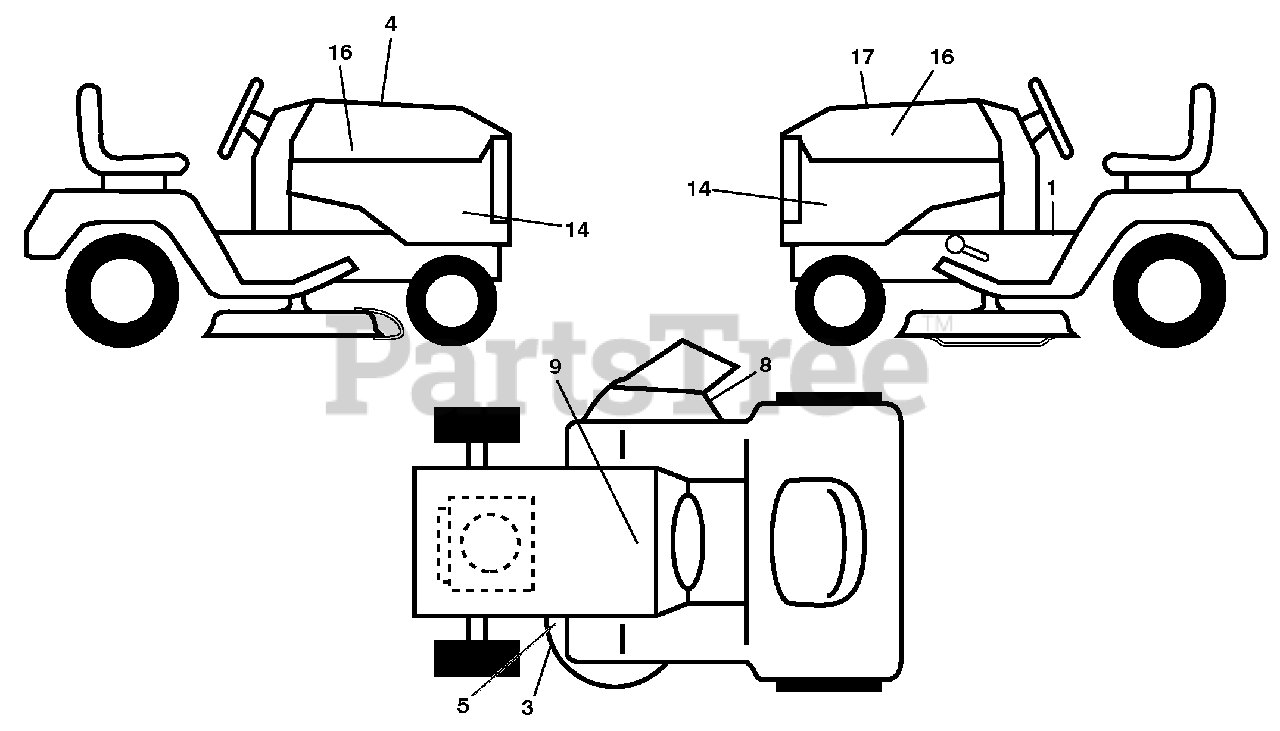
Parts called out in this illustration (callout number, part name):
1	Decal, Fender Warning
3	Decal, Warning
4	Decal, Hood Cust Resp
5	Decal, Mower Caution Tension
8	Decal, Mower Sch.
9	Decal, Battery Dnge/Poi
14	Decal, Panel Side
16	Decal, Hood Logo
17	Decal, Replacement
